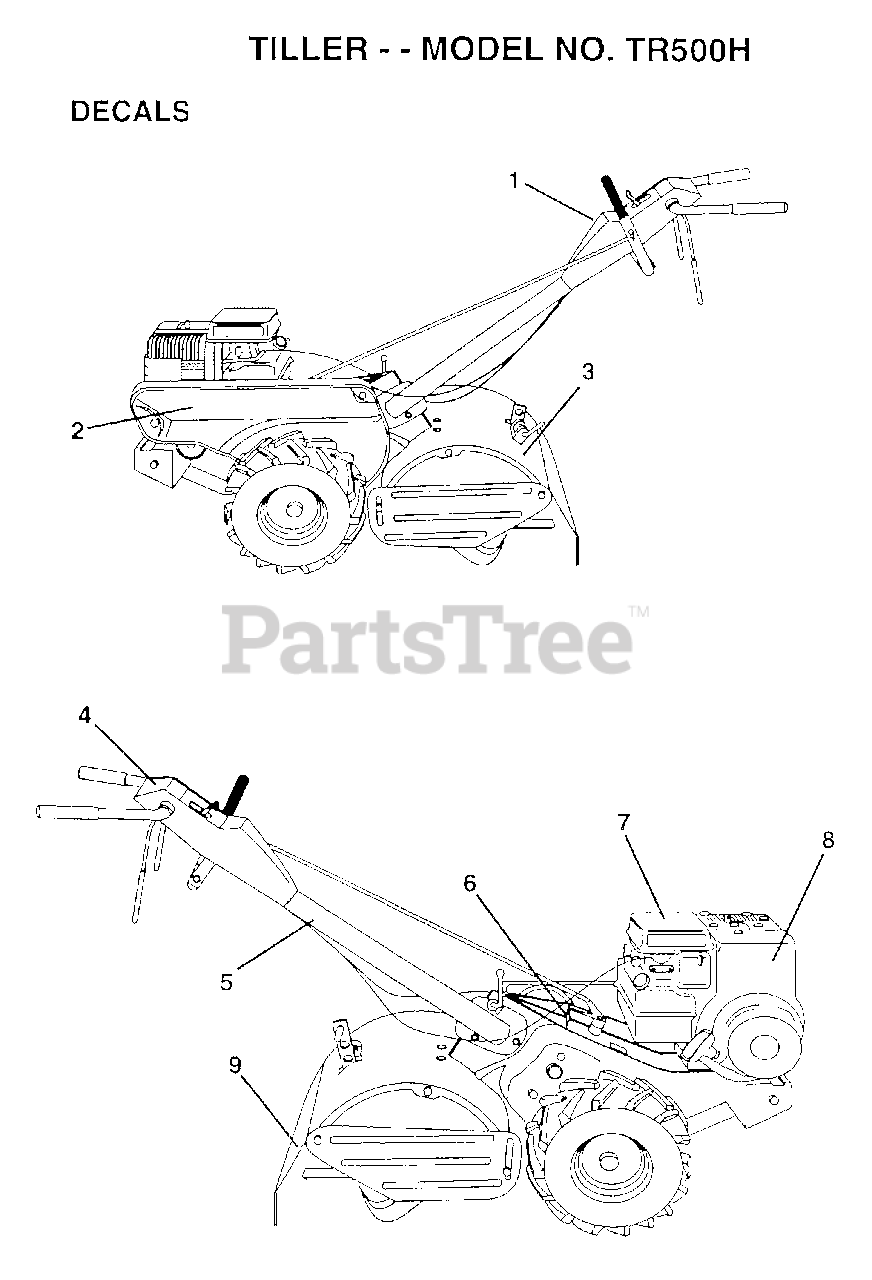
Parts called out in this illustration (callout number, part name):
1	DECAL.PNL.CONTROL
3	DECAL.SHLD.TINE
4	DECAL.INSTRUCTION
5	DECAL TI
6	DECAL CRT
8	DECAL, BRIGGS & STRATTON
9	DECAL TI
